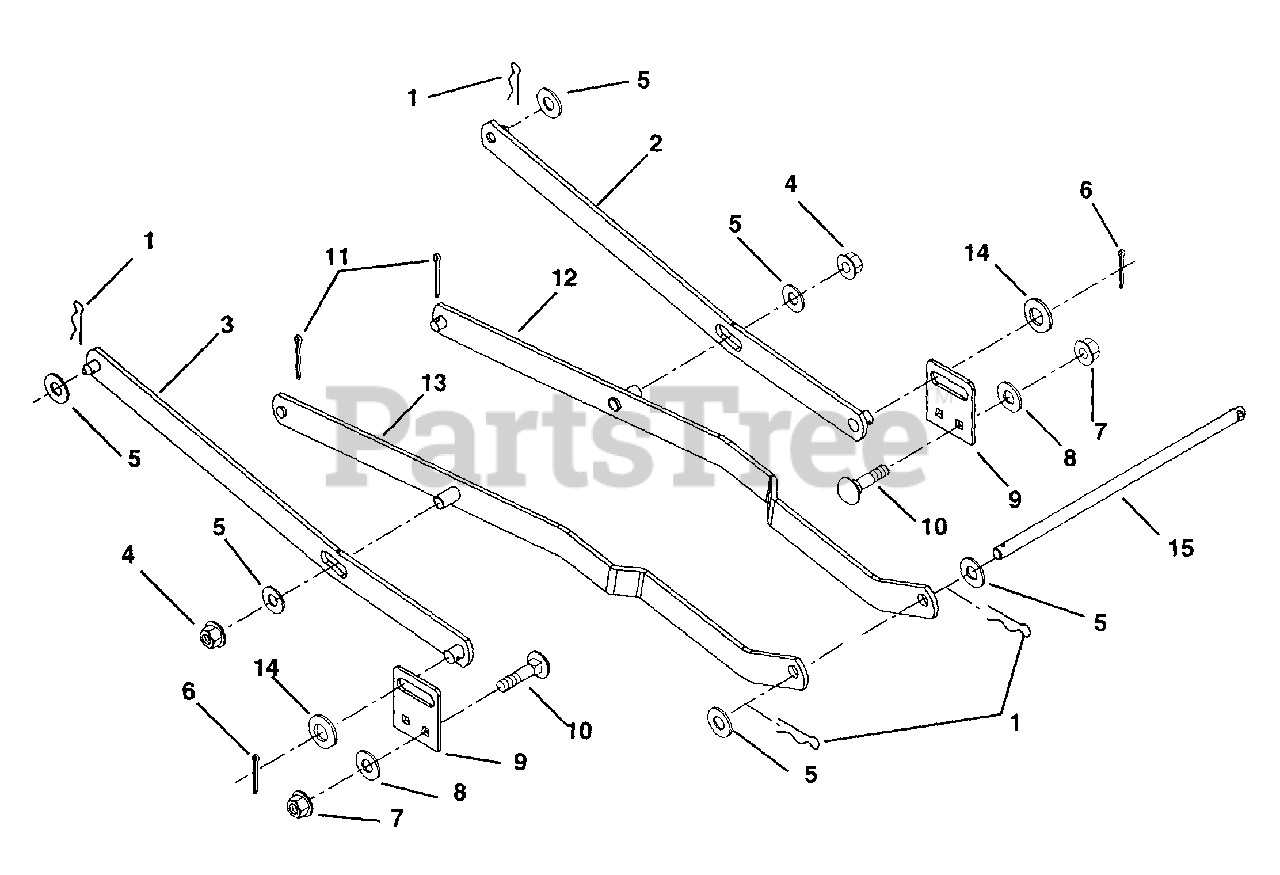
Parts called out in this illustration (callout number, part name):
1	Pin-Hair External .12 x .31 x 2.37
2	Arm-Lift-Left Rear
3	Arm-Lift-Right Rear
4	Nut-Locking-Center .62-11 Grade 2
5	Washer-Flat-Steel .656 x 1.312 x .095
6	Pin-Cotter .15 x 1.25
7	Nut-Locking-Center.38-16 Grade 2
8	Washer-Flat-Steel .406 x .812 x .065
9	Adjuster-Pan
10	Bolt-Round Head Square Neck .38-16 x 1.00 Grade 5
11	Pin-Cotter .12 x 1.25
12	Arm-Lift-Right Forward
13	Arm-Lift-Left Forward
14	Washer-Flat-Steel .630 x 1.005 x .062
15	Rod-Front Hanger
